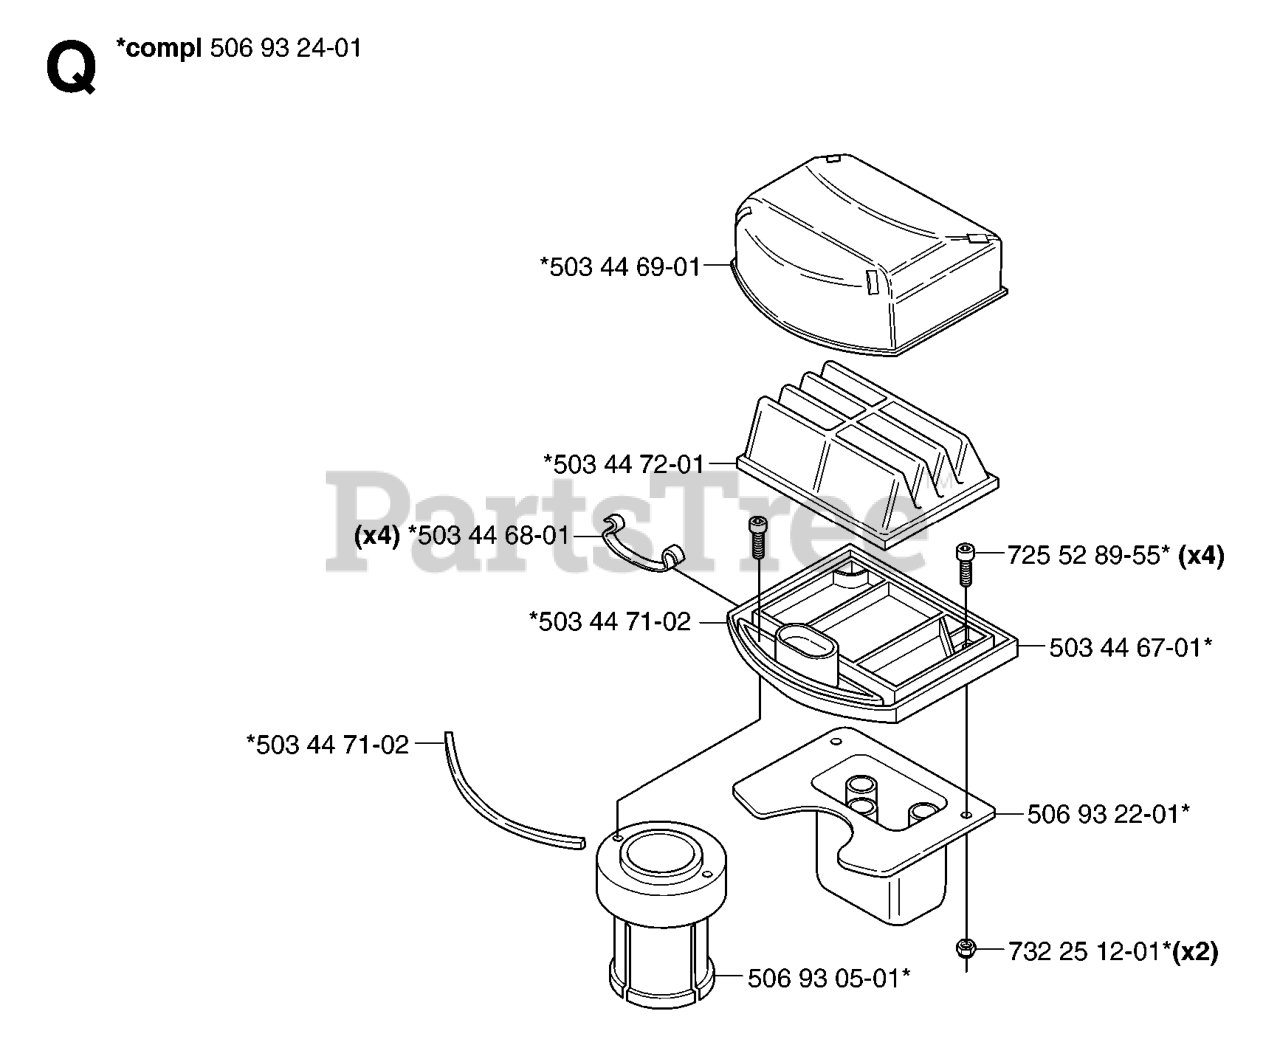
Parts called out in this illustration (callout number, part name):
1	CHOKE CONTROL
2	SCREW LT
4	MUFFLER.LT.BRIGGS.14HP.IC/OHV
13	REPL BY 532 27 22-93
14	Nipple Pipe 3/8 Npt X 3-1/2
15	ELBOW
16	LOCKWASHER
29	KIT.SPARK ARRESTOR 794945 B&S
31	TANK.FUEL(3.5.GAL)
32	FUEL CAP
33	HOSE CLAMP
34	PAD-SPACER LT
35	SCREW.THDROL.5/16-18X3/4.TTY
37	HOSE T
39	PAD IDLER TI
62	WASHER.LOCK.HVY.HLCL.SPR.5/16
72	SCREW
78	SCREW
81	NUT FLANGE 1/4-20 STARTER NUT
